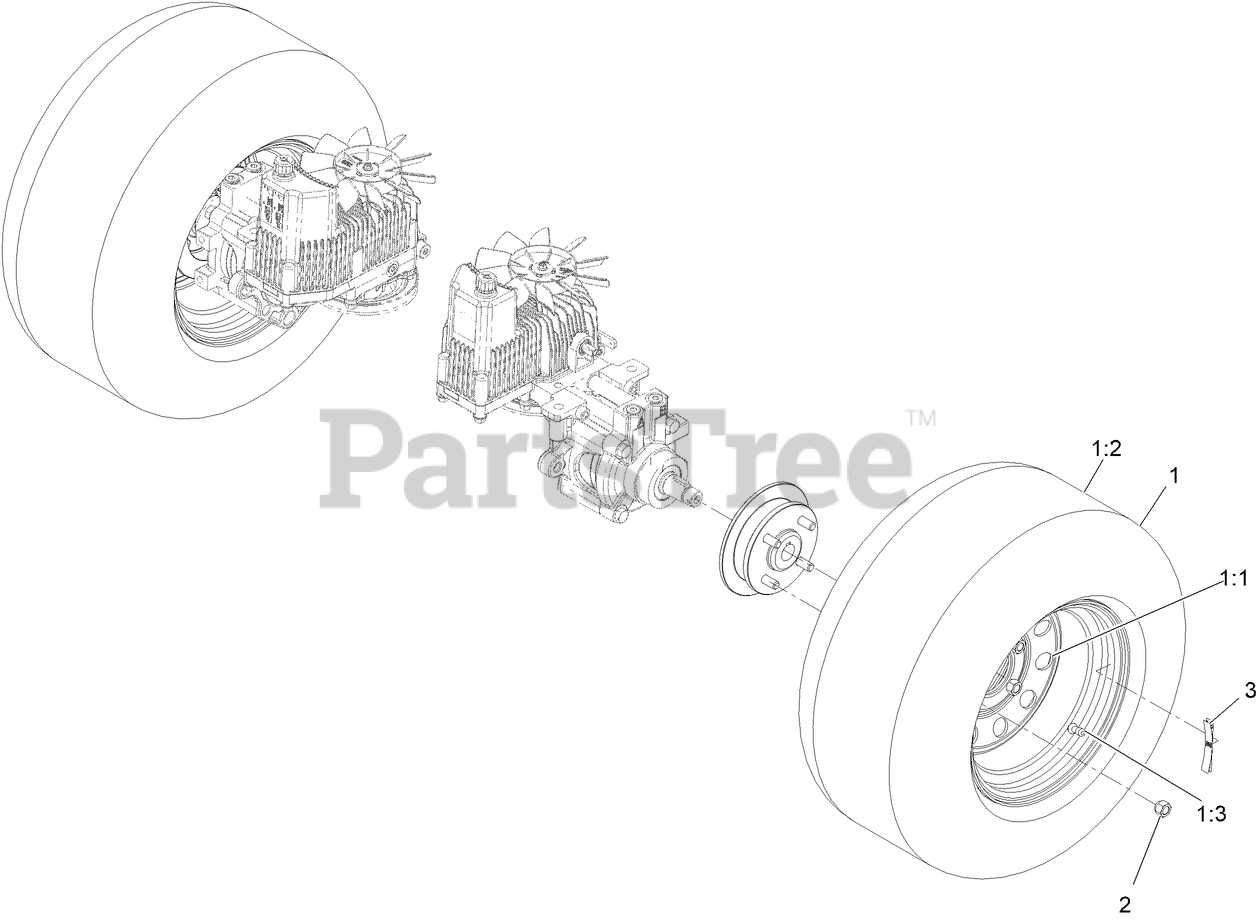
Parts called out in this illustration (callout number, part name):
1	WHEEL AND TIRE ASM
1:1	RIM-GREY
1:2	TIRE-24X12-12
1:3	Stem-Valve
2	NUT-LUG
3	DECAL-TORQUE, WHEEL HUB LUG
